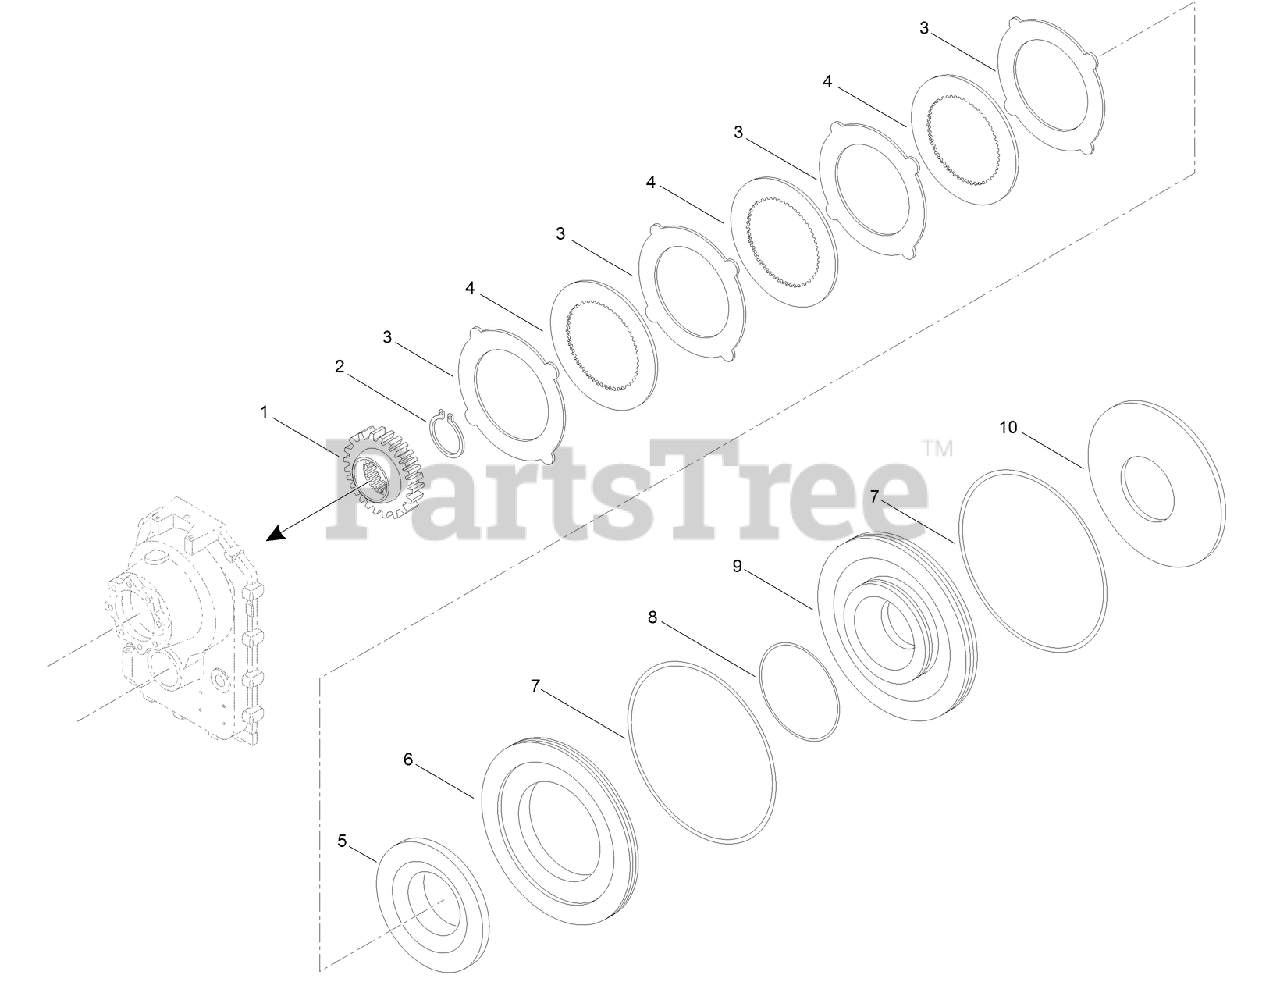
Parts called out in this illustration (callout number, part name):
1	SLEEVE-BRAKE, PARK
2	RING-SNAP
3	PLATE-SEPARATOR
4	PLATE-FRICTION
5	PISTON-PUSHER
6	PLATE-STOP, PISTON
9	PISTON-BRAKE, PARK
10	WASHER-SPRING, BELLVILLE
